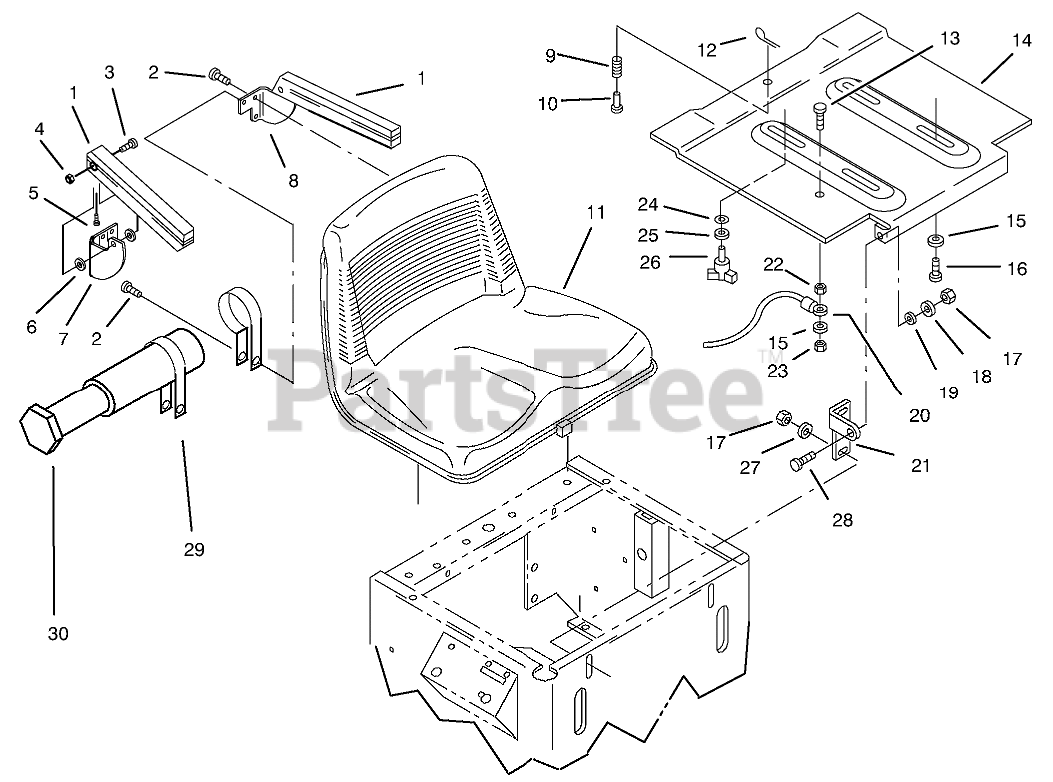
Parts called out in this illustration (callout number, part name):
1	ARMREST
2	3/8-16 X 5/8 SCREW
3	3/8-16X1-1/2 SCREW
4	3/8-16 ACORN LOCKNUT
5	3/8-16 X 3/4 SCREW
6	NYLON SPACER
7	RH ARM BRACKET
8	LH ARM BRACKET
9	SPRING-COMPRESSION
11	Seat
12	PIN-COTTER
13	SCREW-HH
14	PLATE SEAT PIVOT R
15	WASHER-FLAT
16	BOLT 5/16-18X5/8
17	NUT-LOCK, NI
18	WASHER-FLAT
19	SPACER
20	Cable
21	Seat Pivot Bracket RH
22	NUT-HEX
23	NUT-LOCK, NI
24	LOCKWASHER INT EXT
25	WASHER-PLAIN
27	WASHER-FLAT
28	BOLT-CARR
29	CLAMP-R
30	TUBE-MANUAL
